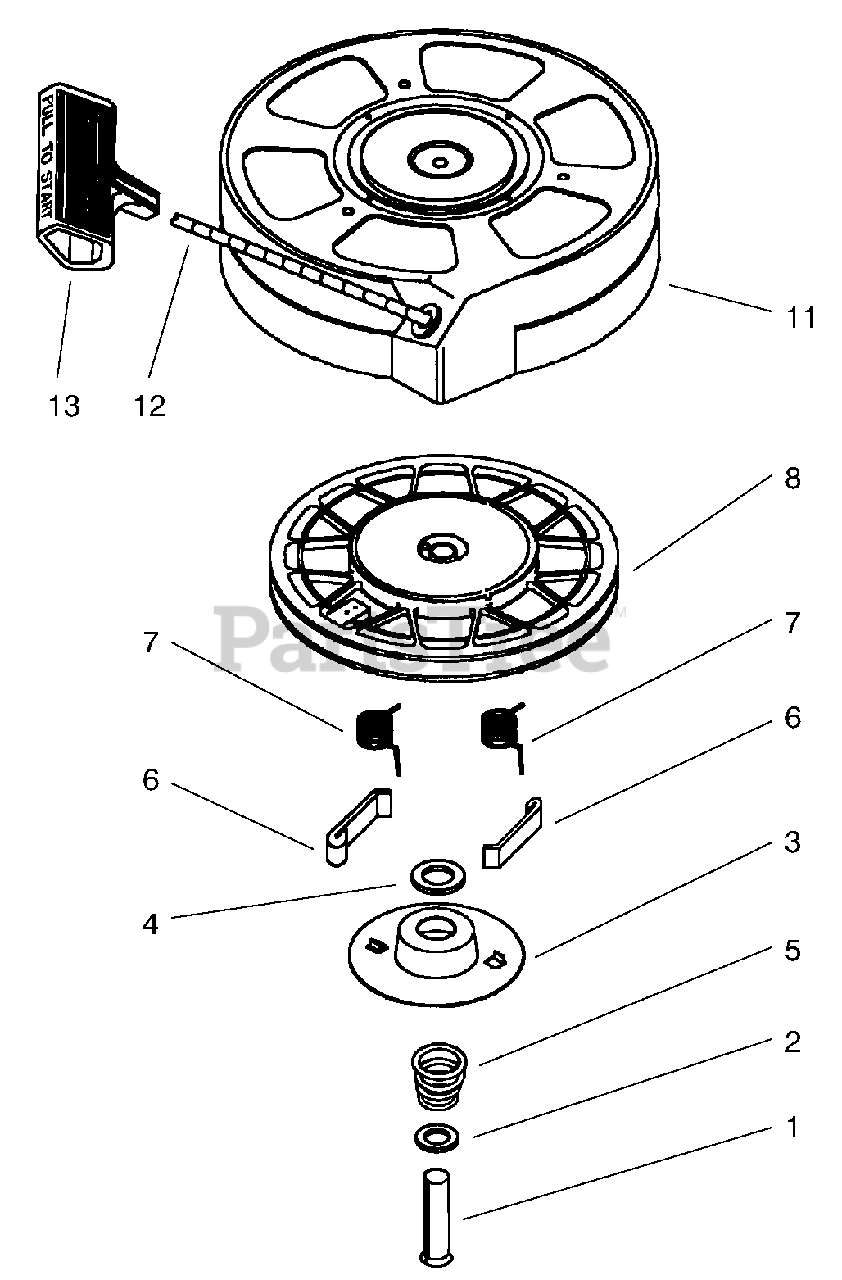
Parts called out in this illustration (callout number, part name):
1	Spring Pin (Incl. Ref. #4)
3	Retainer
5	Brake Spring
6	Starter Dog
7	Dog Spring
8	Pulley & Rewind Spring Assembly
11	Starter Housing Assembly
12	Starter Rope
13	Starter Handle
